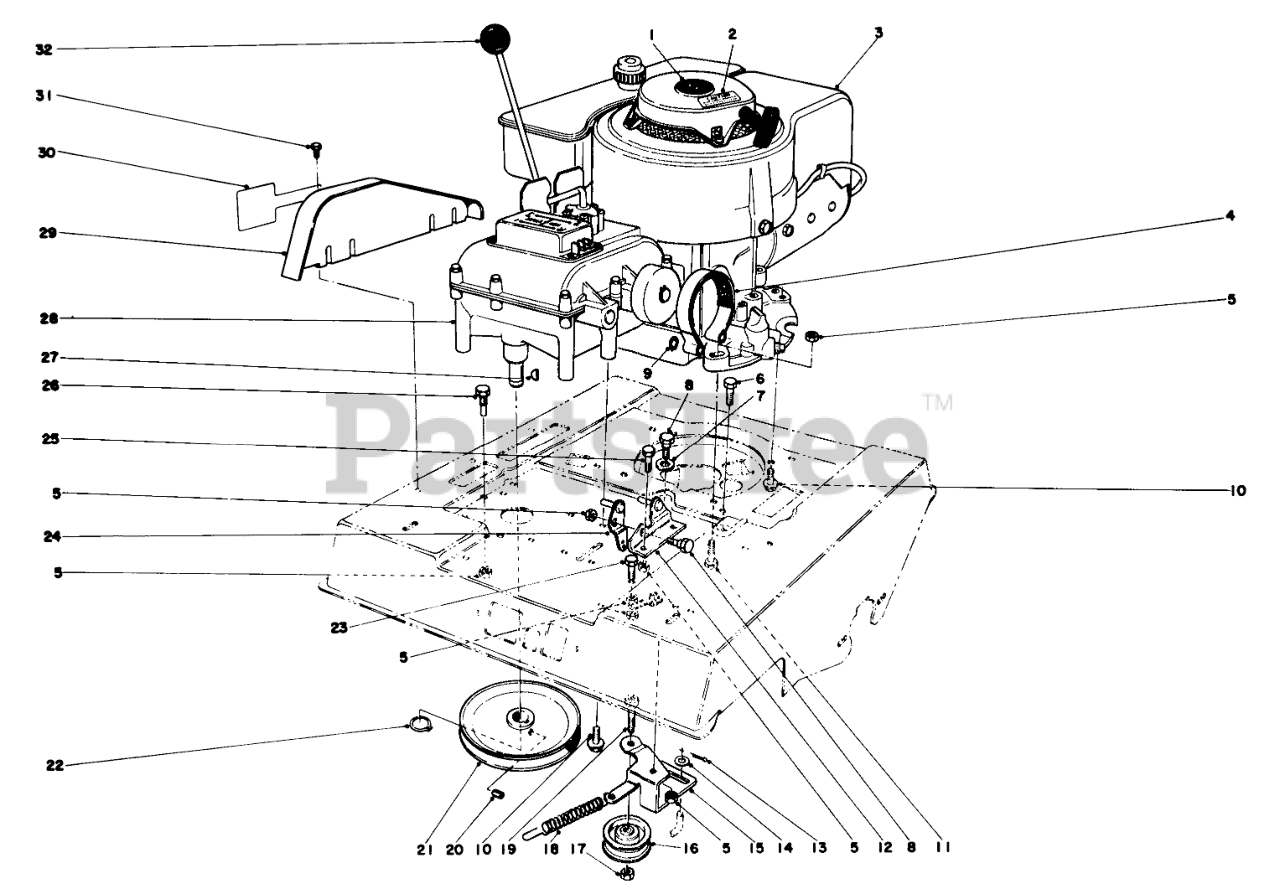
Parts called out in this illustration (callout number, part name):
1	Decal "5"
2	Caution Decal
3	Engine for (Model 56005)
4	Brake Band
5	NUT-LOCK, CONE
6	SCREW-HH
7	Washer
8	Screw
9	RING-GRIP
10	SCREW-HHF
11	SCREW-HH
12	Bracket
13	PIN-COTTER
14	WASHER-PLAIN
15	Idler Lever
16	PULLEY IDLER
17	NUT-LOCK, CONE
18	Clutch Spring
19	Capscrew
20	SCREW-SET, HSH
21	Pulley
22	Ring Retainer
23	SCREW-HH
24	Pivot
25	SCREW-HH
26	Screw
27	KEY-WOODRUFF
28	Transmission
29	Chain Guard
30	Decal Shift Pattern
31	SCREW-HWH
